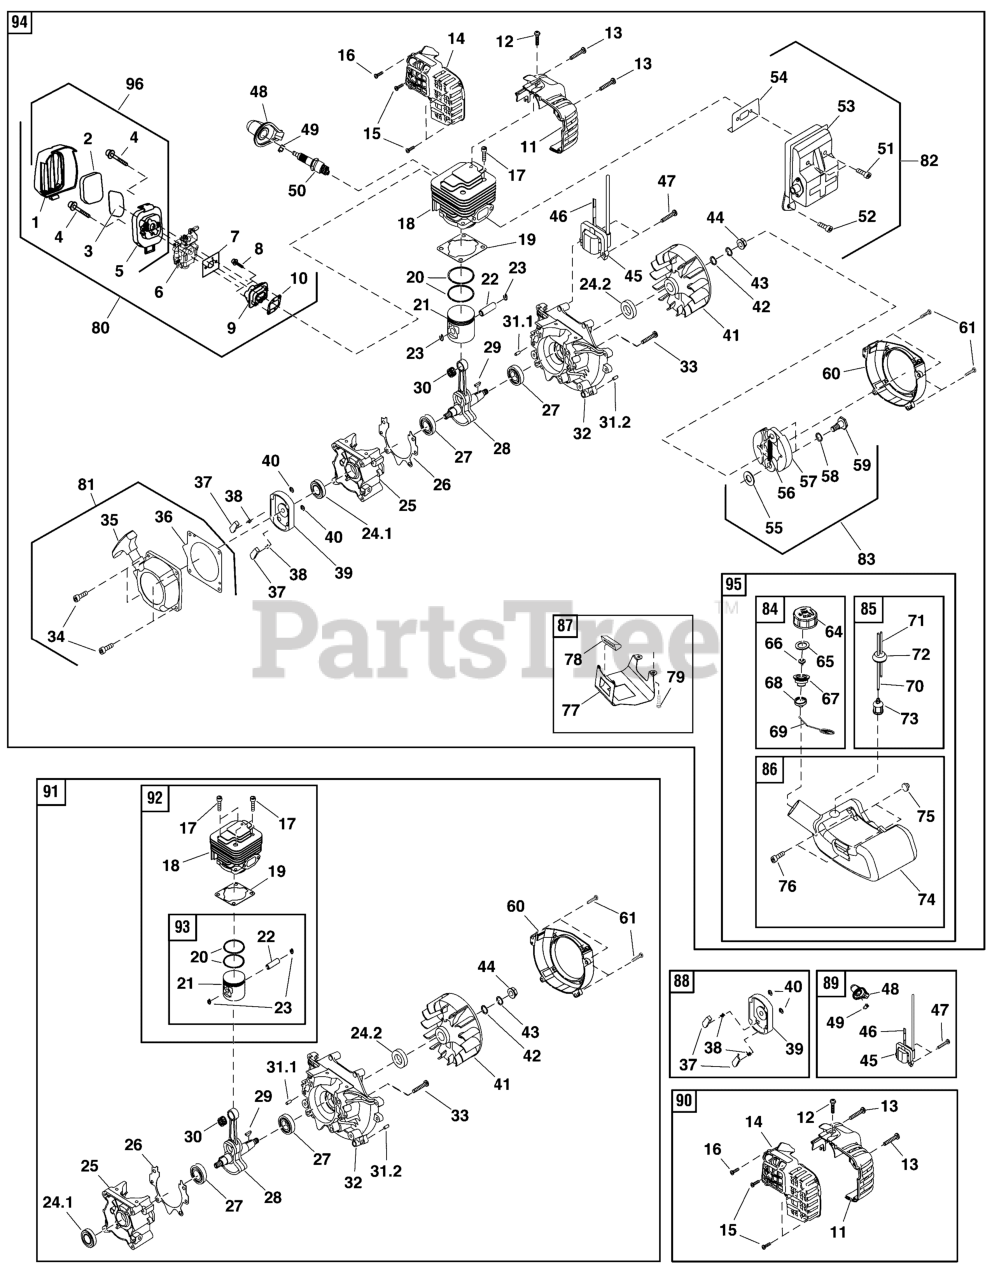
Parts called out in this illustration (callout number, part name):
1	COVER, Cleaner, Outer
2	FILTER
3	BRACKET, Filter Net
4	BOLT, M5 x 55
5	BRACKET, Air Cleaner
6	CARBURETOR, Ruixing
7	GASKET, Carburetor
8	BOLT, M5 x 25
9	ADMITTING PIPE
10	GASKET, Admitting Pipe
11	SHROUD, Front
14	SHROUD, Back
15	SCREW, Self Tapping, 5 x 20
16	SCREW, Self Tapping, 4.2 x 25
17	BOLT, M5 x 20
18	CYLINDER
19	GASKET, Cylinder
20	RING, Piston
21	PISTON
22	PIN, Piston
23	RING, Pin Retain
24.1	SEAL, Oil, 11.7 x 22 x 7
24.2	OIL SEAL, 30 x 14.7 x 7
25	CRANK CASE, Rear
26	GASKET, Crank Case
27	BEARING, 6201/P6
28	CRANKSHAFT
29	KEY, 3 x 5 x 13
30	BEARING, Needle
31.1	PIN, Cylindrical, B5 x 12
31.2	PIN, Cylindrical, B4 x 10
32	CRANK CASE, Front
35	STARTER
36	STARTER PAD
37	STARTER CINCH
38	SPRING, Starter
39	STARTER BOX
40	RING, Retainer
41	FLY WHEEL
42	WASHER, Flat, Dia. 8
43	WASHER, Spring, Dia. 8
44	NUT, M8
45	MAGNETO COIL
46	CORD, Magneto
48	BOOT, Spark Plug
49	CLIP, Spark Plug
50	SPARK PLUG
51	* BOLT, M5 x 55-10.9
53	MUFFLER
54	GASKET, Muffler
55	WASHER, B
56	SPRING, Clutch
57	EXPANDER, Complete
58	WASHER, Wave
59	SCREW, Shaft
60	COVER, Fan
61	BOLT, M5 x 25
64	LID, Fuel Tank
65	GASKET
66	INLET
67	LID, Fuel Tank, Inner
68	COVER, End
69	CHAIN, Fuel Cap
70	PIPE, Fuel
71	PIPE, Soft PVC
72	PLUG, Fuel Line
73	FILTER, Fuel
74	FUEL TANK
75	PLUG, Rubber
77	BRACKET, Fuel Tank
78	COVER, Rubber
80	KIT, Air Cleaner & Carburetor
81	KIT, Starter Assembly
82	KIT, Muffler Assembly
83	KIT, Expander Assembly
84	KIT, Fuel Cap Assembly
85	KIT, Fuel Line Assembly
86	KIT, Fuel Tank Assembly
87	KIT, Tank Bracket Assembly
88	KIT, Start Reel Assembly
89	KIT, Magneto Assembly
90	KIT, Shroud Assembly
91	KIT, Cylinder Assembly
92	KIT, Cylinder Head Assembly
93	KIT, Piston Assembly
94	ENGINE ASSEMBLY, Complete
95	KIT, Fuel Tank & Cap
96	KIT, Air Cleaner
